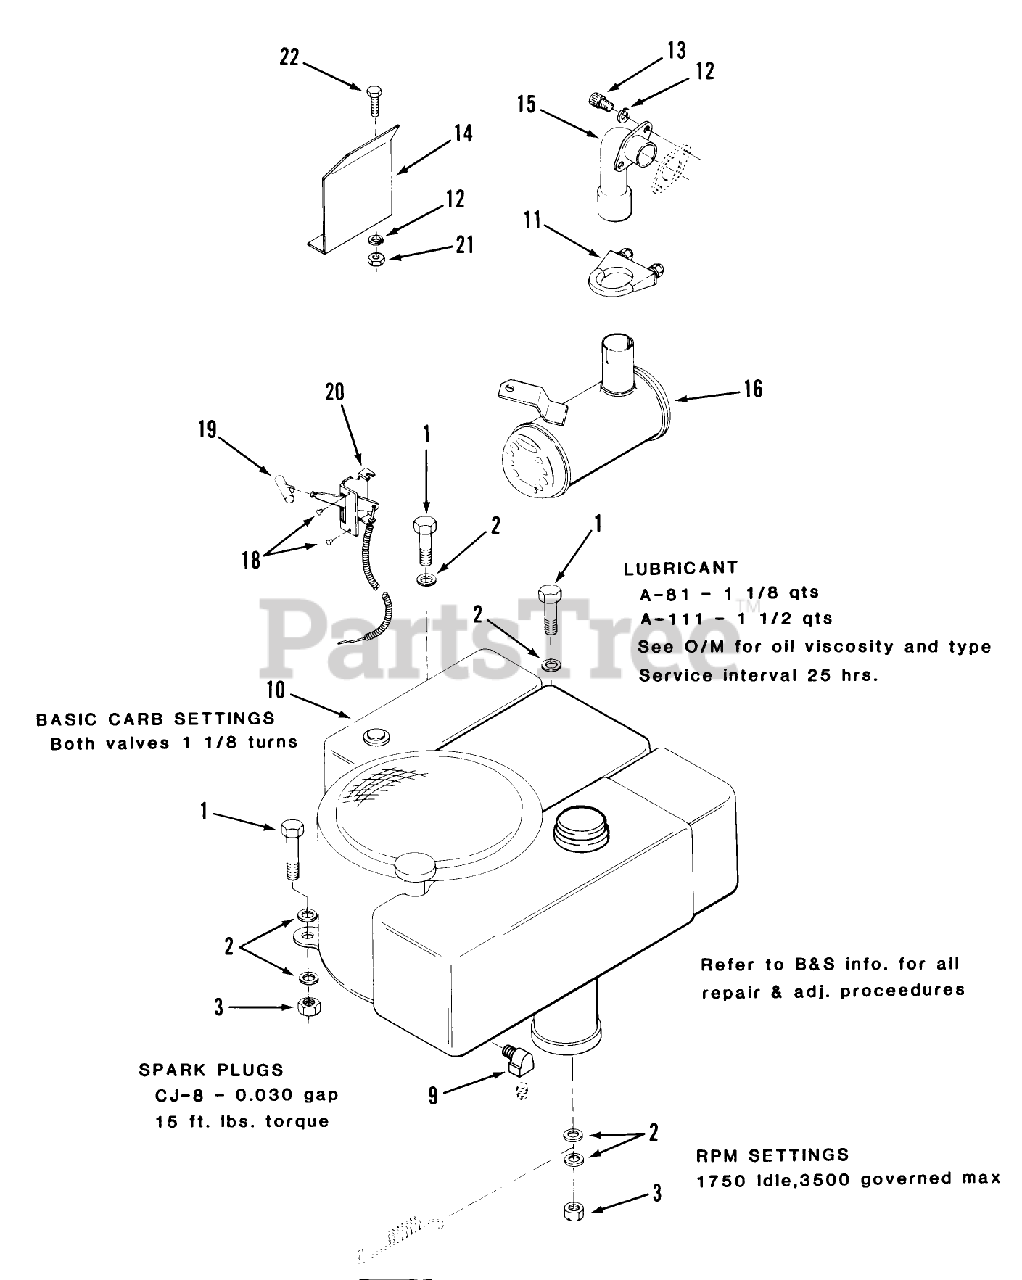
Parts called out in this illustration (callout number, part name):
2	WASHER 5/16 SAE
2	WASHER
10	Engine 8 H.P.-BS Model 191707 Type 5821-01 A-81 Only
10	Engine 11 H.P.-BS Model 252707 Type 0648-01 A-111 Only
13	SHCS 5/16-18X.625
18	RIVET
